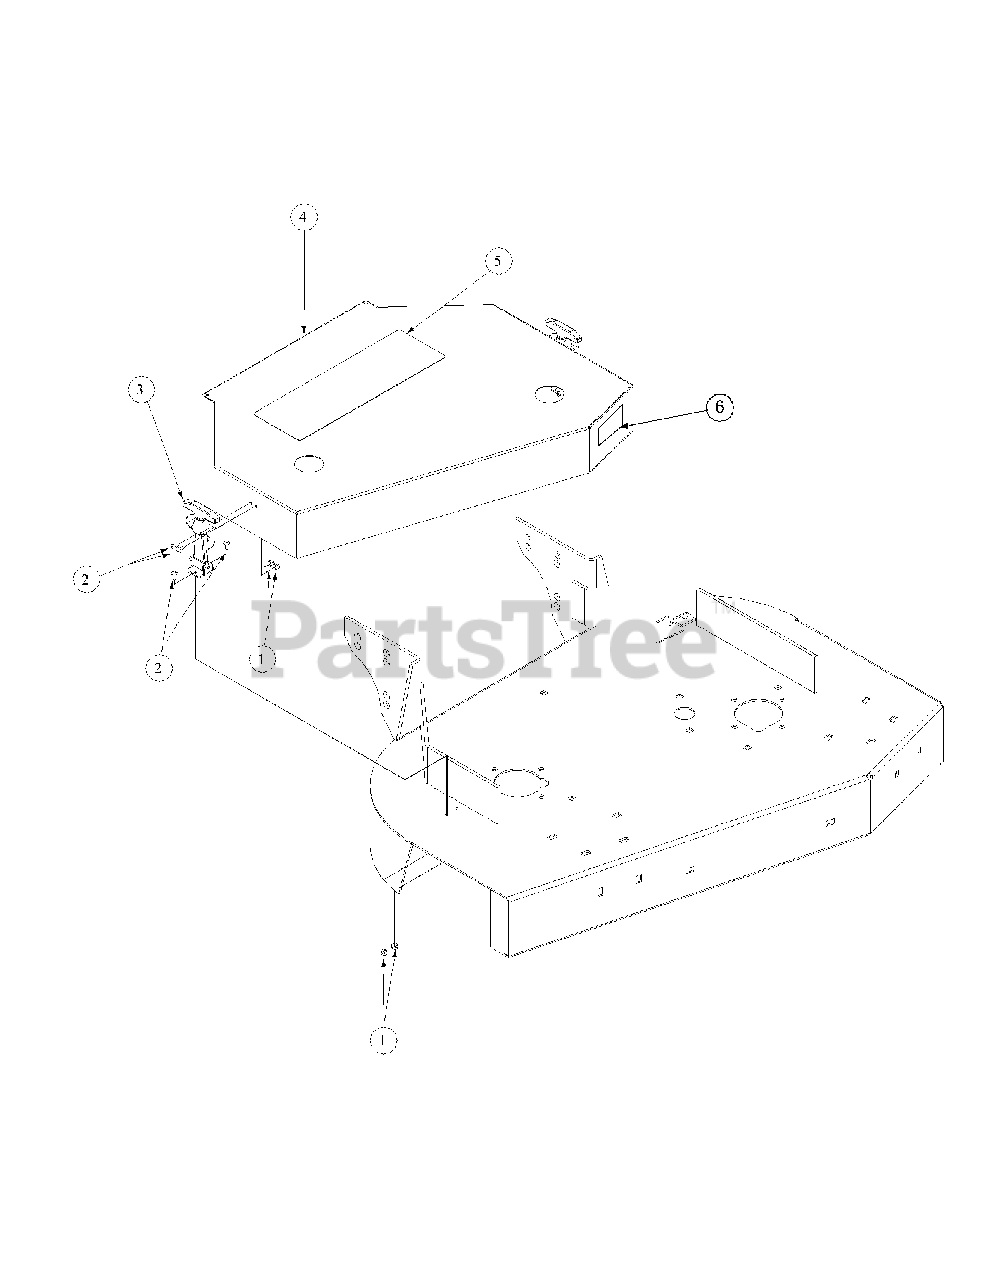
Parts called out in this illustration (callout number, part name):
1	Lock Nut, Nylon Insert #10-24
2	Machine Screw, 10-24 x 1/2
3	Rubber Hood Latch
4	Deck Cover, 36
5	Label Commercial Mower
6	Label, H1536
